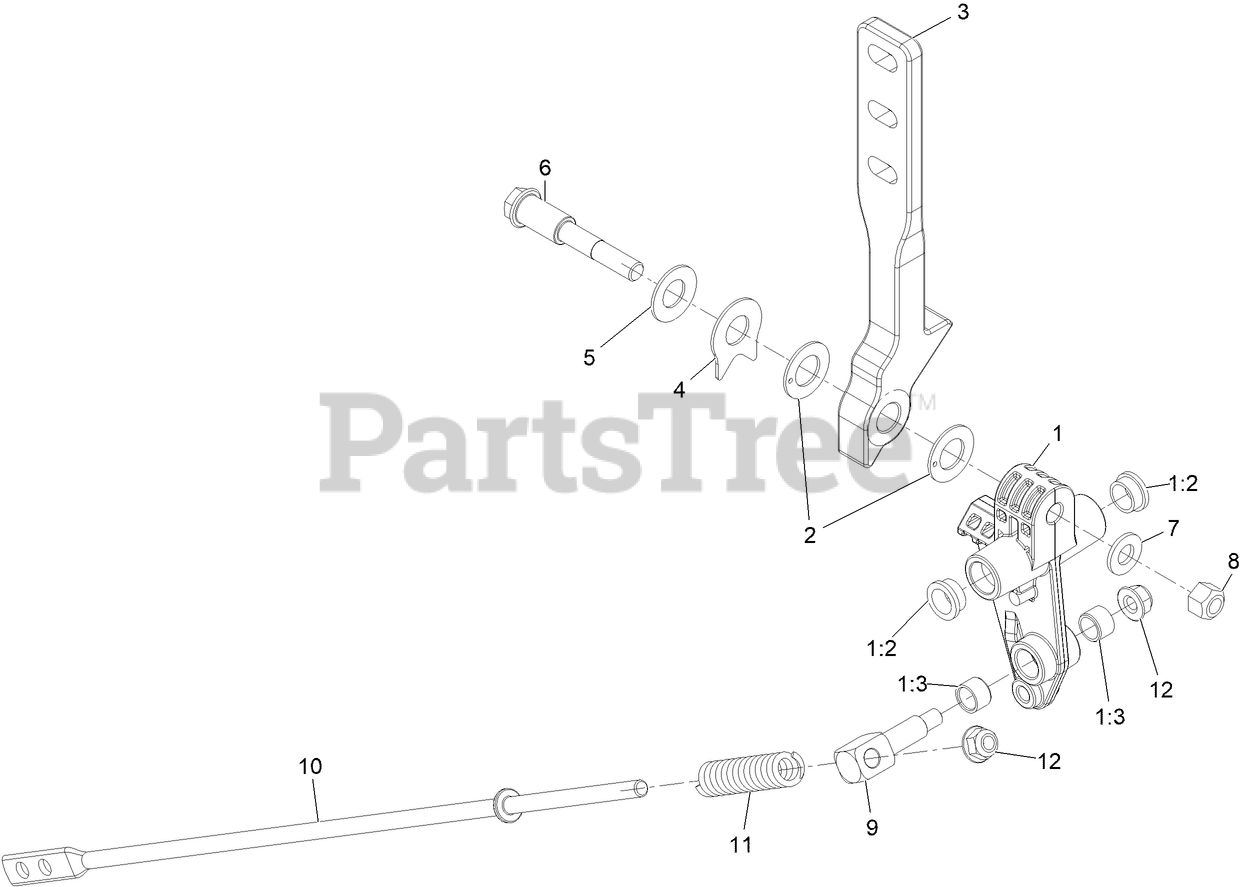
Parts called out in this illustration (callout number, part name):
1	CONTROL ARM ASM
1:2	BUSHING
1:3	BUSHING-SLEEVE
2	WASHER-FRICTION
3	Lever, Motion Control
4	Spacer, Anti-Rotation
5	WASHER-BELLEVILLE
6	Bolt-Pivot
7	WASHER-FLAT
8	NUT-LOCK, CONE
10	Link, Motion Control
11	Spring, Compression
12	NUT-HF, NI
